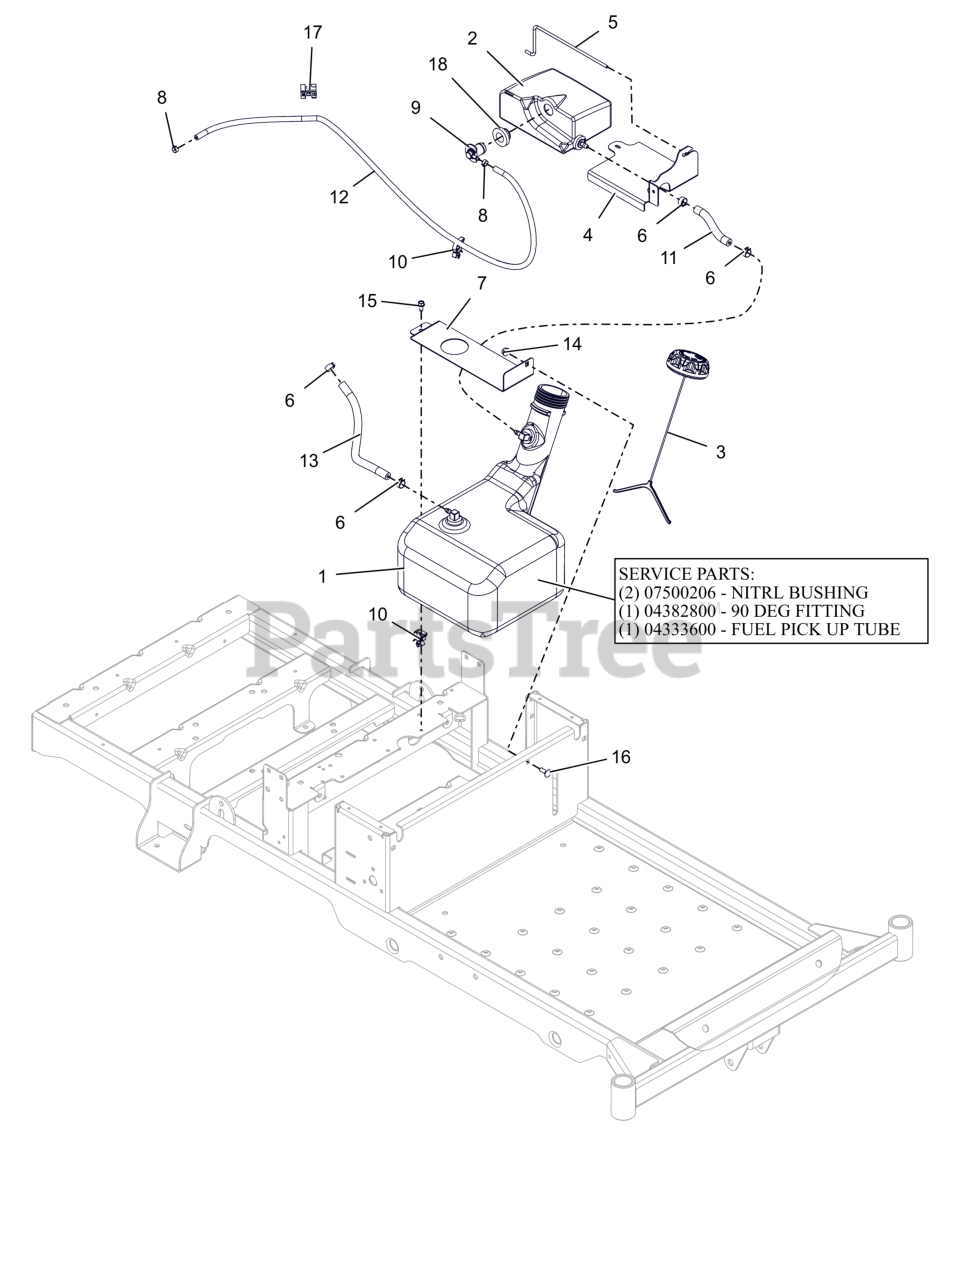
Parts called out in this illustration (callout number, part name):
1	ASM, FUEL TANK-ZOOM
1	BSHG-FLG .375X1.062X.625 NITR
1	FITTING, 90 DEG FUEL-PLASTIC
1	FUEL PICK UP TUBE
2	ASM, FUEL TANK - EXPANSION
3	CAP, FUEL VENT-IN 2.25" RATCH.
4	BRKT, EXPANSION TANK (ORANGE)
5	ROD, HOLDDOWN (BLACK)
6	CLAMP, FUEL LINE
7	BRKT, TANK STRAP
8	CLAMP-HOSE, SPRING .188
9	VALVE, 2-WAY
10	WIRE CLIP
11	HOSE, .25 LOW-PERM BULK GAS
12	HOSE, .188 LOW-PERM BULK GAS
13	HOSE, .25 LOW-PERM BULK GAS
14	NUT-LK-CTR-FLG .25-20 ZC120
15	SCR-TAP .25-20X.50 HWH ZCC
16	BLT, RHSN .25-20X.750 G5 ZCC
17	CLIP, T, .38-.50
18	GROMMET, REMOTE VENT NITRILE
